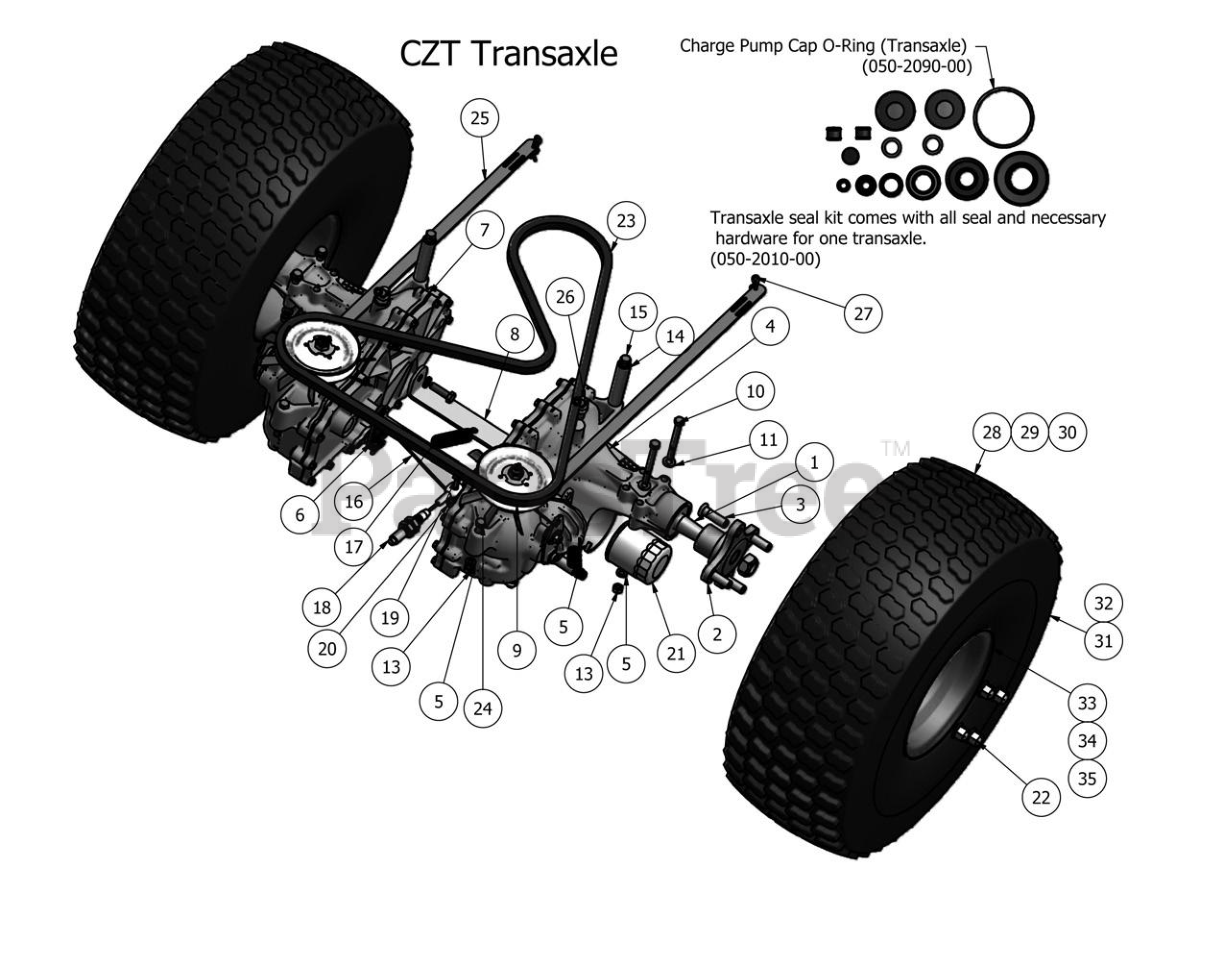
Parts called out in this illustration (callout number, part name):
1	Axle Shaft
4	Left CZT Transaxle
5	Transaxle Spring
6	Transaxle Brake Lever
7	Right CZT Transaxle
8	Crossover Bar for CZT
9	Fan/Pulley Kit For CZT
10	5/16" x 3" Hex Bolt
11	5/16" Flat Washer
14	3 1/4" Spacer
15	5/16" x 6" Bolt
16	CZT Crossover Brake
18	Brake Cable Short
19	1/4" x 3/4" Hex Bolt
20	1/4" Nylock Nut
22	1/2"Acorn Nut
24	5/16" x 2 1/2" Bolt
25	Transaxle Neutral Lever
26	45 Deg Fitting
27	Hear Pin Cotter Clip
28	23 x 10.50-12 Tire & Wheel
29	23 x 10.50-12 Tire & Wheel (50" Only)
30	23 x 8.50-12 Tire & Wheel (42" Only)
31	23 x 10.50-12 Tire
32	23 x 8.50-12 Tire
33	23 x 10.50-12 Wheel (60"Only)
34	23 x 10.5-12 Wheel (50" Only)
35	23 x 8.50-12 Wheel (42" Only)
